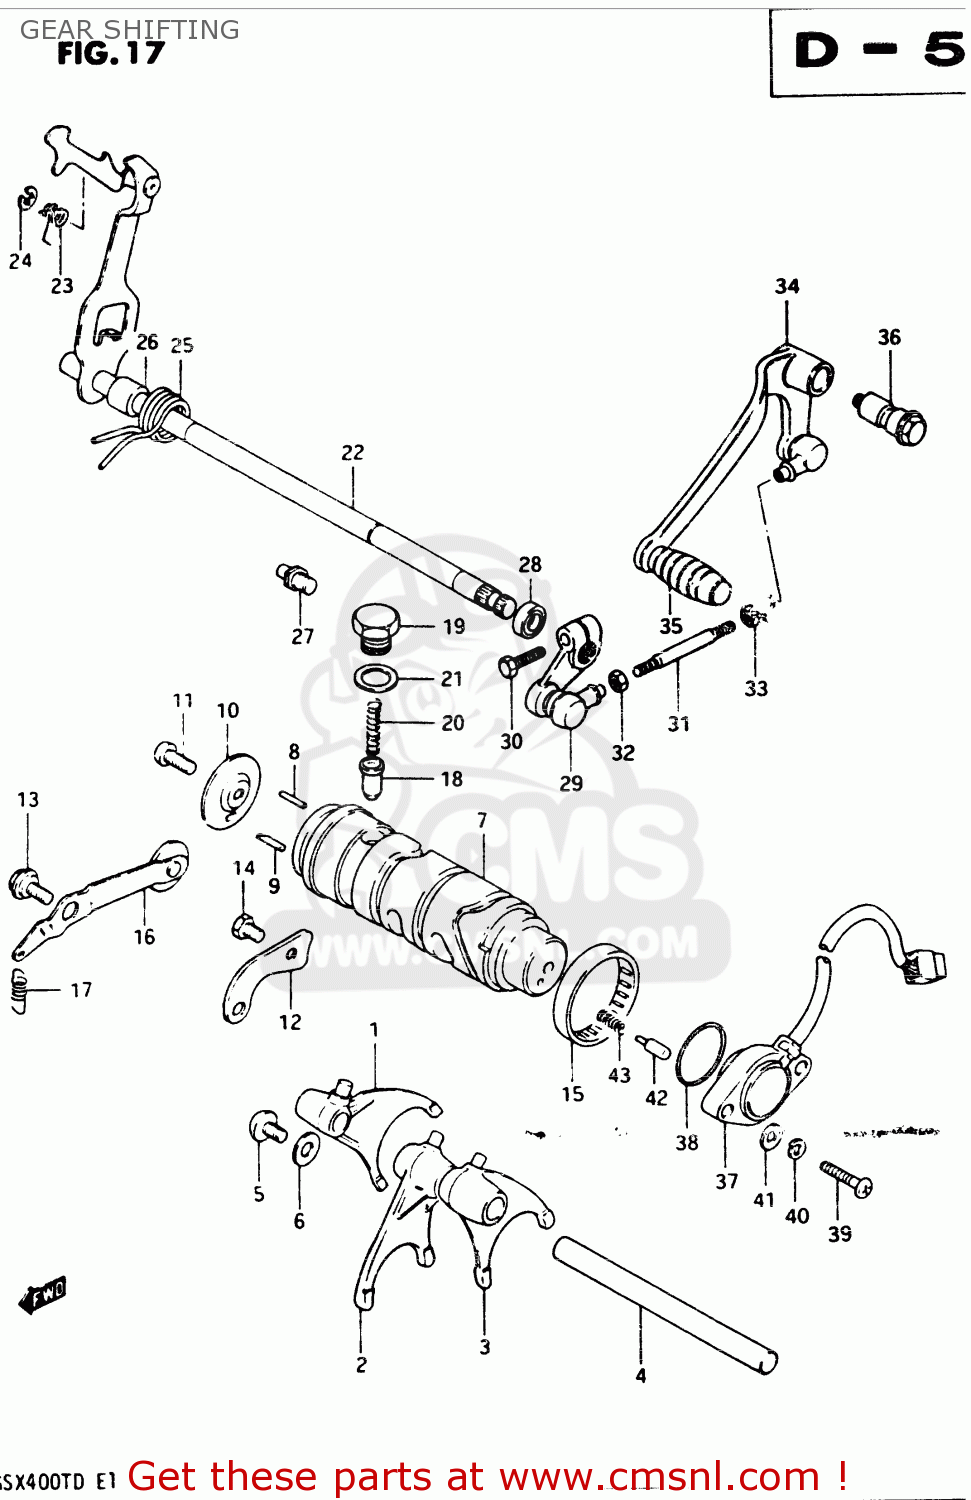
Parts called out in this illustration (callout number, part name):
1	FORK,GEAR SHIFT NO.1
2	FORK,GEAR SHIFT NO.2
3	FORK,GEAR SHIFT NO.2
4	SHAFT,GEAR SHIFT FORK
5	SCREW
6	WASHER
7	CAM,GEAR SHIFT
8	PIN(4X18.5)
9	PIN
10	RETAINER,GEAR SHIFT CAM DR PIN
11	SCREW
12	GUIDE,GEAR SHIFTING CABLE
13	BOLT
14	BOLT, UPPER
15	BEARING(40X47X12)
16	STOPPER,GEAR SHIFT CAM NO.1
17	SPRING
18	STOPPER,GEAR SHIFT CAM NO.2
19	HOLDER,GEAR SHIFT CAM STOP SPR
20	SPRING
21	GASKET(14X19.2X2) (NAS)
22	SHAFT,GEAR SHIFT
23	SPRING
24	E RING
25	SPRING
26	SPACER(12X20X15.3)
27	STOPPER,GEAR SHIFT CAM
28	OIL SEAL
29	ARM,GEAR SHIFT LINK
30	BOLT
31	ROD,GEAR SHIFT LINK
32	NUT
33	NUT
34	LEVER ASSY,GEAR SHIFT
35	RUBBER,GEAR SHIFT PEDAL
36	SHAFT,GEAR SHIFT LEVER
37	BASE ASSEMBLY,NEUTRAL SWITCH TERMINAL
38	O-RING (D:2.4 ID:26.2)
39	SCREW 5X20
40	LOCK WASHER
41	WASHER
42	PIN(5X15.5)
43	SPRING
